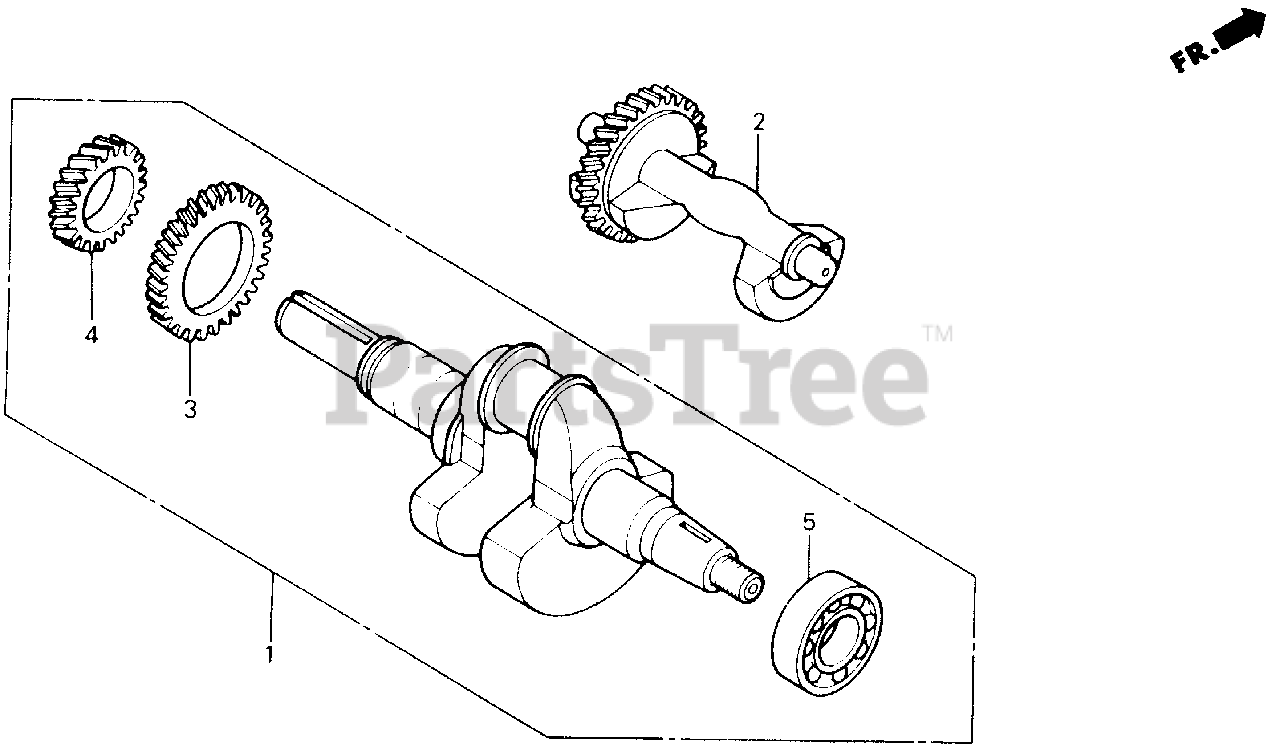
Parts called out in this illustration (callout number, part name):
1	CRANKSHAFT
2	WEIGHT, BALANCER
5	BEARING, RADIAL BALL (6207S)
